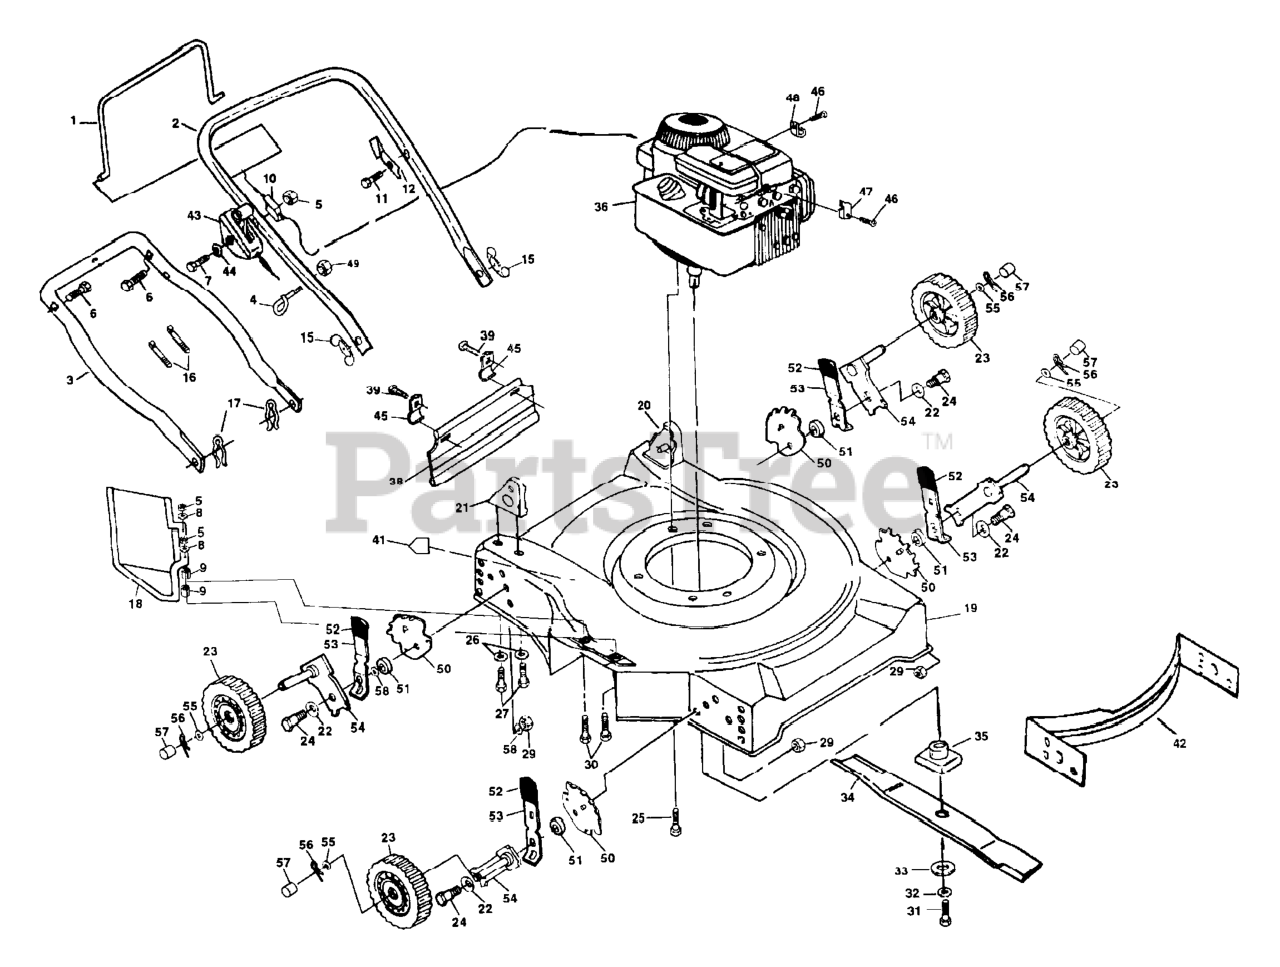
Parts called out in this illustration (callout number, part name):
1	CONTROL BAR
2	UPPER HANDLE
3	HANDLE, LOWER PM
4	ROPE GUIDE
5	NUT
6	HANDLE BOLT
7	SCREW**
8	WASHER
10	CABLE.MZR.51.RT.SP./PU.
11	TAPPING SCREW
12	BRACKET UPSTOP
15	NUT WING PM
16	TIE GUIDE
17	HAIRPIN COTTER
18	GUARD-DISCHARGE
19	HOUSING ASSEMBLY NLA
20	HANDLE BRKT ASSY LH
21	HANDLE BRKT ASSY RH
22	WASHER.BELLEVILLE (3 2 LB)
23	Wheel & Tire Assembly 7.0 x 1-1/2
24	SHOULDER BOLT PM
25	BOLT
26	STEEL WASHER
27	SCREW
29	LOCKNUT PM
30	Bolt, Fin Hex 1/4 - 20 x 1 1/2
31	SCREW, HEX HD 3/8-24 X 1-3/8
32	LOCKWASHER
33	WASHER,HARDEN
34	20" Blade
35	BLADE ADAPTOR
38	REAR SKIRT
39	TAPPING SCREW
41	DECAL HYT
42	FRONT BAFFLE
43	THROTTLE CONTROL
45	BRACKET DEFL PM
46	SCREW.HEX.HEAD.WASHER.10-16
47	WASHER
48	GUIDE CLIP PM
49	NUT
50	WHEEL ADJUST BRACKET
51	SPACER PM
53	SELECTOR SPRING
54	AXLE ARM
56	RETAINER CLIP PM
58	WASHER
